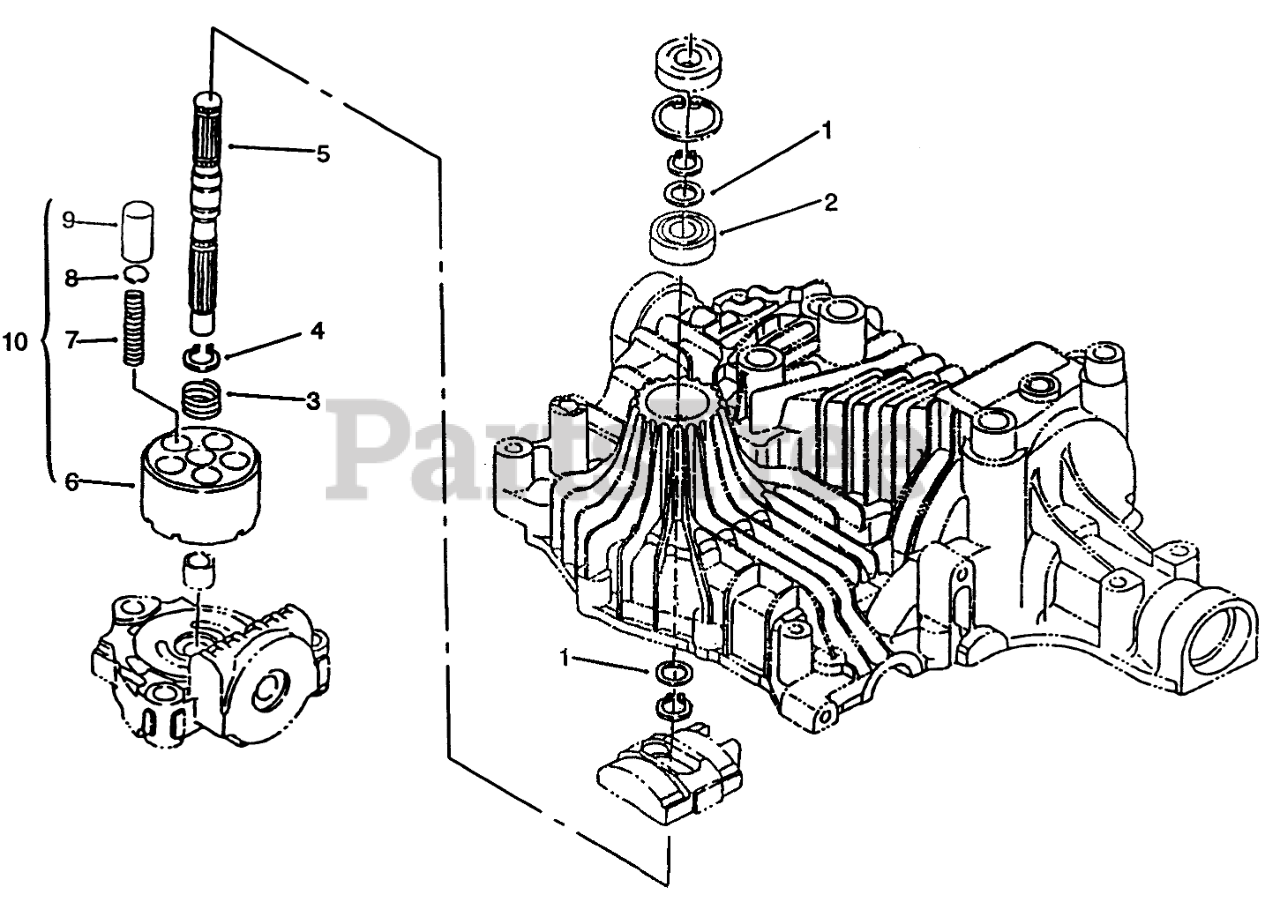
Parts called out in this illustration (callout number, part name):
1	Washer (Only On: 72083, 72043, 72103, 72063)
2	Bearing-Ball (Only On: 72083, 72043, 72103, 72063)
3	Spring (Only On: 72083,72043,72103,72063)
4	Ring-Snap (Only On: 72083,72043,72103, 72063)
5	Shaft-Pump (Only On: 72083,72043,72103, 72063)
10	Cylinder ASM INC 6-9 (Only On: 72083,72043, 72103, 72063)
